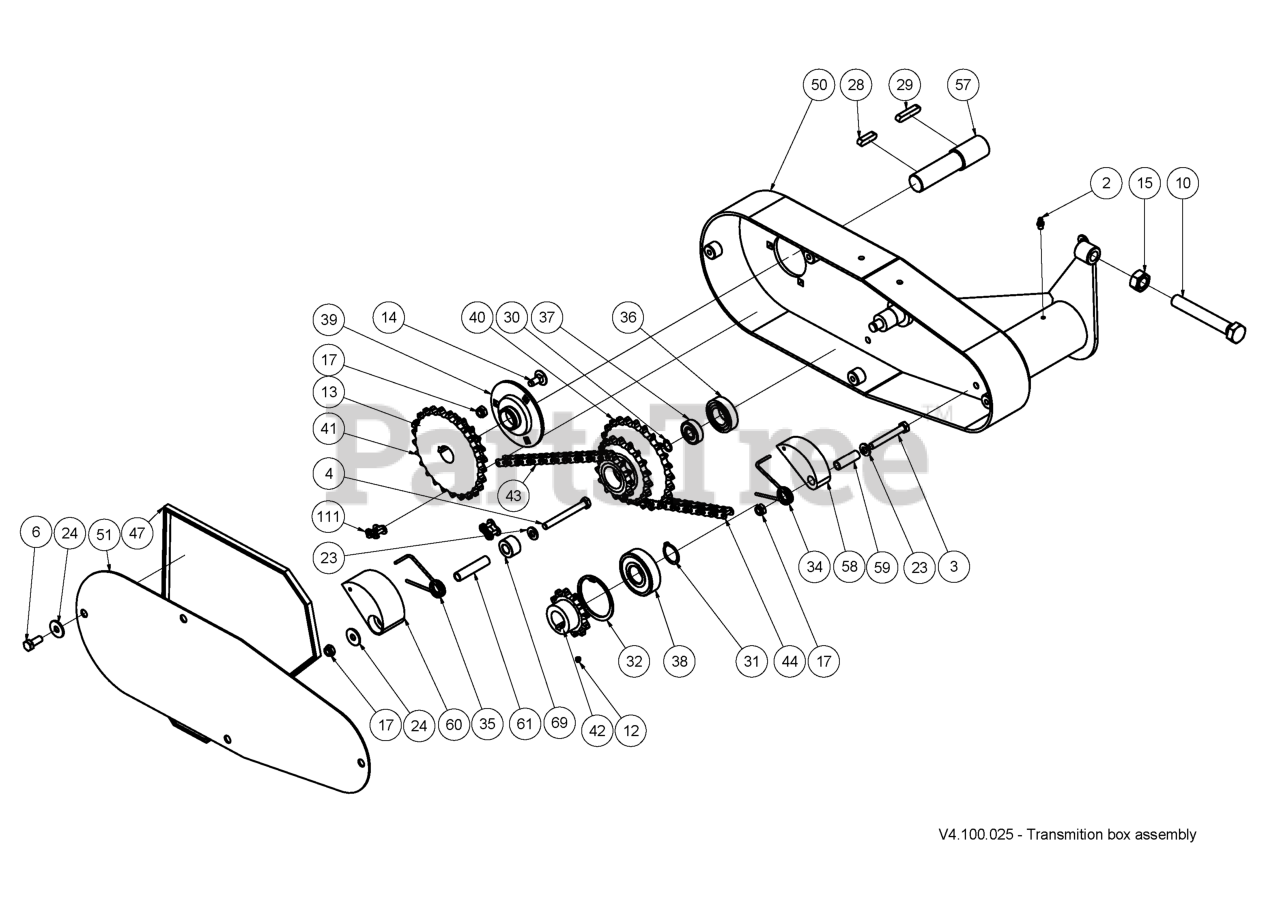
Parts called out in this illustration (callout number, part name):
17	LOCKNUT M8
23	WASHER BRB 8.4X17
30	RETAINING RING SGA 10
